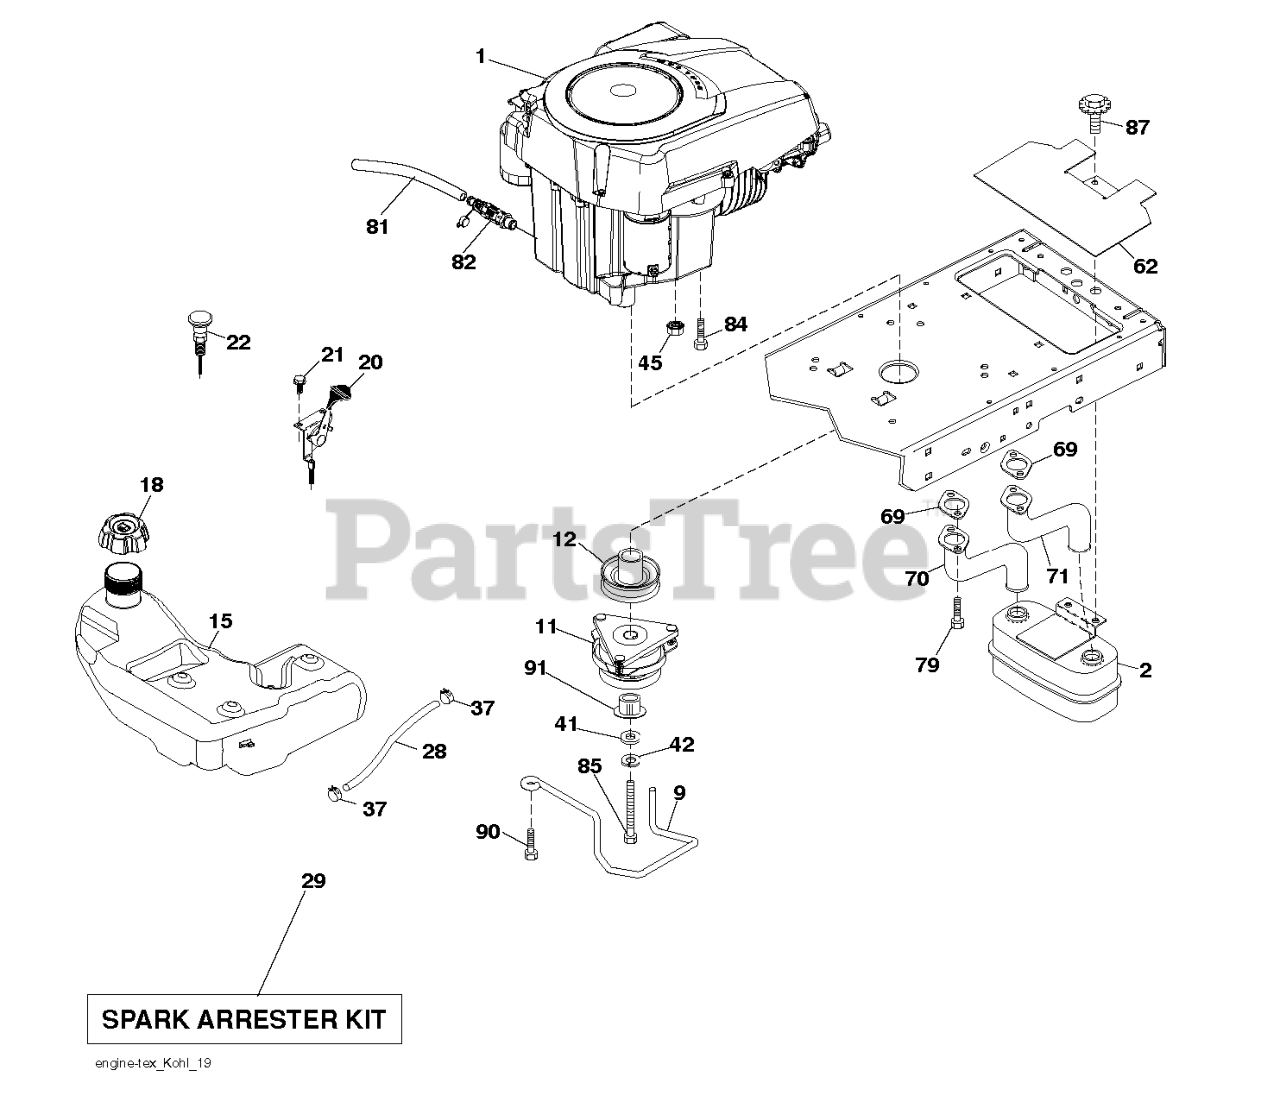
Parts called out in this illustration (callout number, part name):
2	MUFFLER.TWIN.CYL.LOW.TONE
9	KEEPER.BELT.ENGINE.4.2
11	CLUTCH MZ ZTR GT.48/54"1.125"
12	PULLEY ENGINE
15	TANK.FUEL.4GAL
18	CAP.FUEL.TANK.3"GREY
20	THROTTLE CONTROL
21	SCREW.#10 X 0.750.BOS
22	CONTROL.CHOKE.ERGO.PUSH-IN.BLA
28	LINE.FUEL.64"REAR.EMIS
29	KIT.SPARK ARRESTOR 794945 B&S
37	HOSE CLAMP
42	LOCKWASHER
45	NUT
62	RP SHIELD HEAT MUFFLER
69	GASKET.EXHAUST.KOHL.CV18-CV26
70	RP.PIPE-EXHAUST LH
71	RP.PIPE-EXHAUST RH
79	SCREW.SOCKET HD.5/16-1
81	TUBE, DRAIN OIL ASM.
82	VALUE.OIL.DRAIN
84	SCREW 3/8-16X1
85	BOLT HEX 7/16-20 X 3.75 GR. 5
87	BOLT.5/16-18UNCX1.W/SEMS.BLK
90	SCREW 3/8-16X1
91	BUSHING.1.375OD
